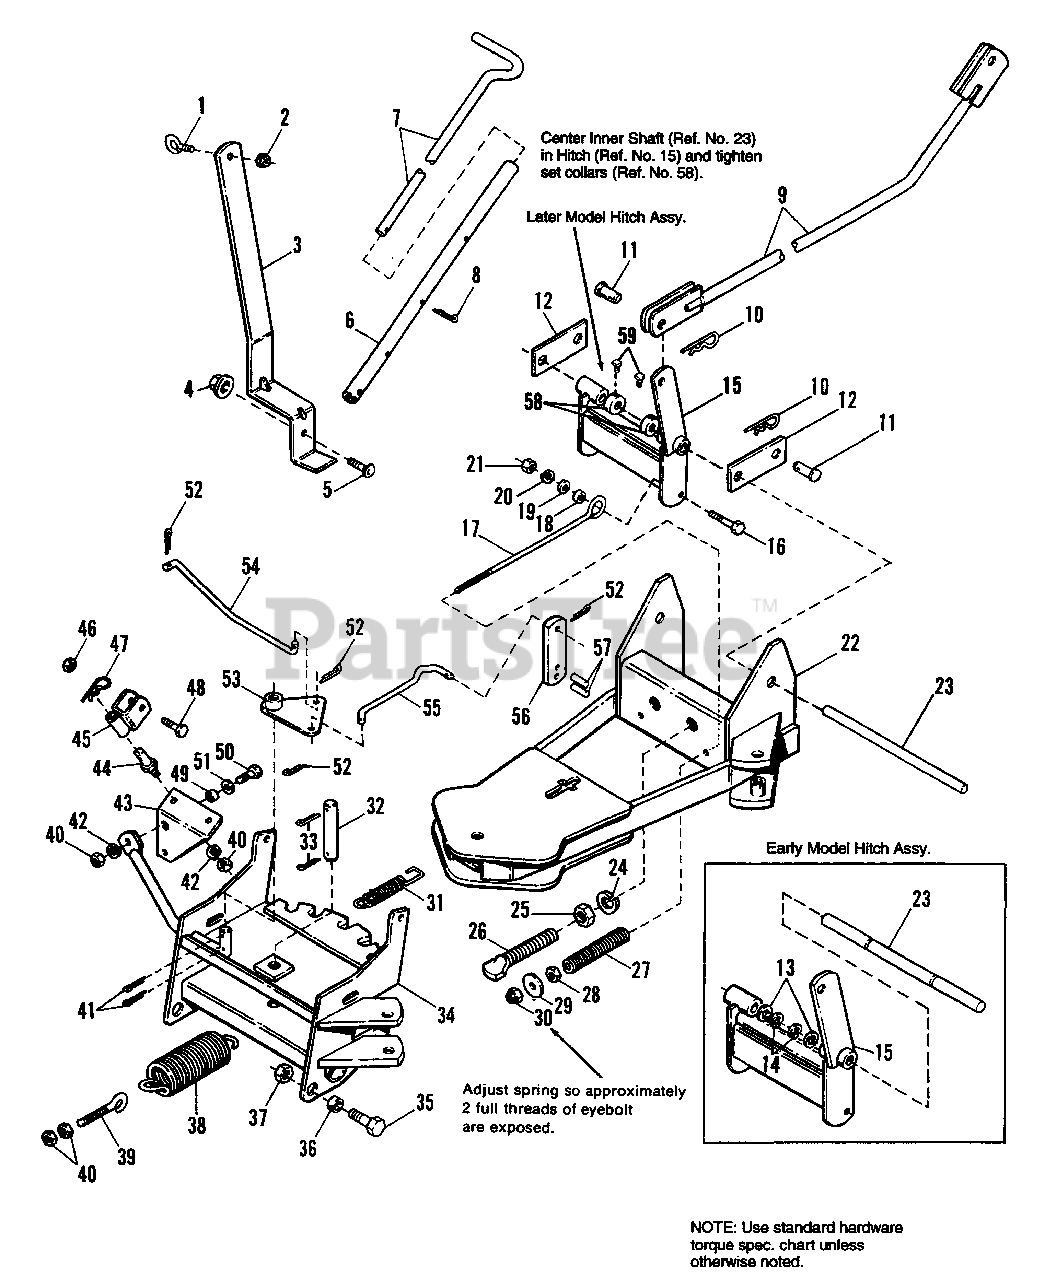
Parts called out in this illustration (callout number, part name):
2	NUT, Hex Lock, 1/4-20
3	SUPPORT, Control Rod
4	NUT, Hex, Flange Whizlock, 3/8-16
5	BOLT, Carriage, 3/8-16 x 1-1/4
6	SLEEVE, Connector
7	HANDLE, Pivot
8	PIN, Cotter, 1/8 x 1, Plt.
9	LIFT ROD ASSY.
10	CLIP, Spring
11	PIN, Clevis
13	WASHER, Plain, 41/64 x 1-1/4 x 1/16
14	E-RING, Retaining, 5/8
15	HITCH ASSY.
16	CAPSCREW, Hex Hd., 5/8-11 x 2
19	WASHER, Plain, 41/64 x 1-3/4 x 1/8
20	LOCKWASHER, 5/8 Std.
21	NUT, Hex, 5/8-11
22	HITCH ASSY, Dozer
23	SHAFT, Inner, Hitch
24	LOCKWASHER, 3/4 Std.
25	NUT, Hex, 3/4-10
26	STUD, 3/4-10 UNC-2A
27	SPRING, Compression
28	NUT, Jam, Hex, 3/8-16
29	WASHER, 13/32 x 1-1/4 x 1/4
30	NUT, Hex, 3/8-16
33	Pin, Cotter, 3/16 x 1-1/4
34	FRAME ASSY., Pivot
35	CAPSCREW, Hex Hd., 1/2-13 x 1-1/2
37	NUT, Hex, Lock, 1/2-13
38	SPRING, Tension
40	NUT, Hex, 5/16-18
41	PIN, Cotter, 1/4 x 1
42	LOCKWASHER, 5/16 Std.
46	NUT, Hex, Lock, 5/16-18
47	CLIP, Spring
48	CAPSCREW, Hex Hd., 5/16-18 x 1-1/2
50	CAPSCREW, Hex Hd., 5/16-18 x 1
51	WASHER, 5/16 Std.
52	PIN, Cotter, 3/32 x 3/4
53	PLATE ASSY., Pivot
57	PIN, Spring, 7/32 x 1
58	SET COLLAR
59	SET SCREW, Sq. Hd. cup point, 5/.16-18 x 1/2
